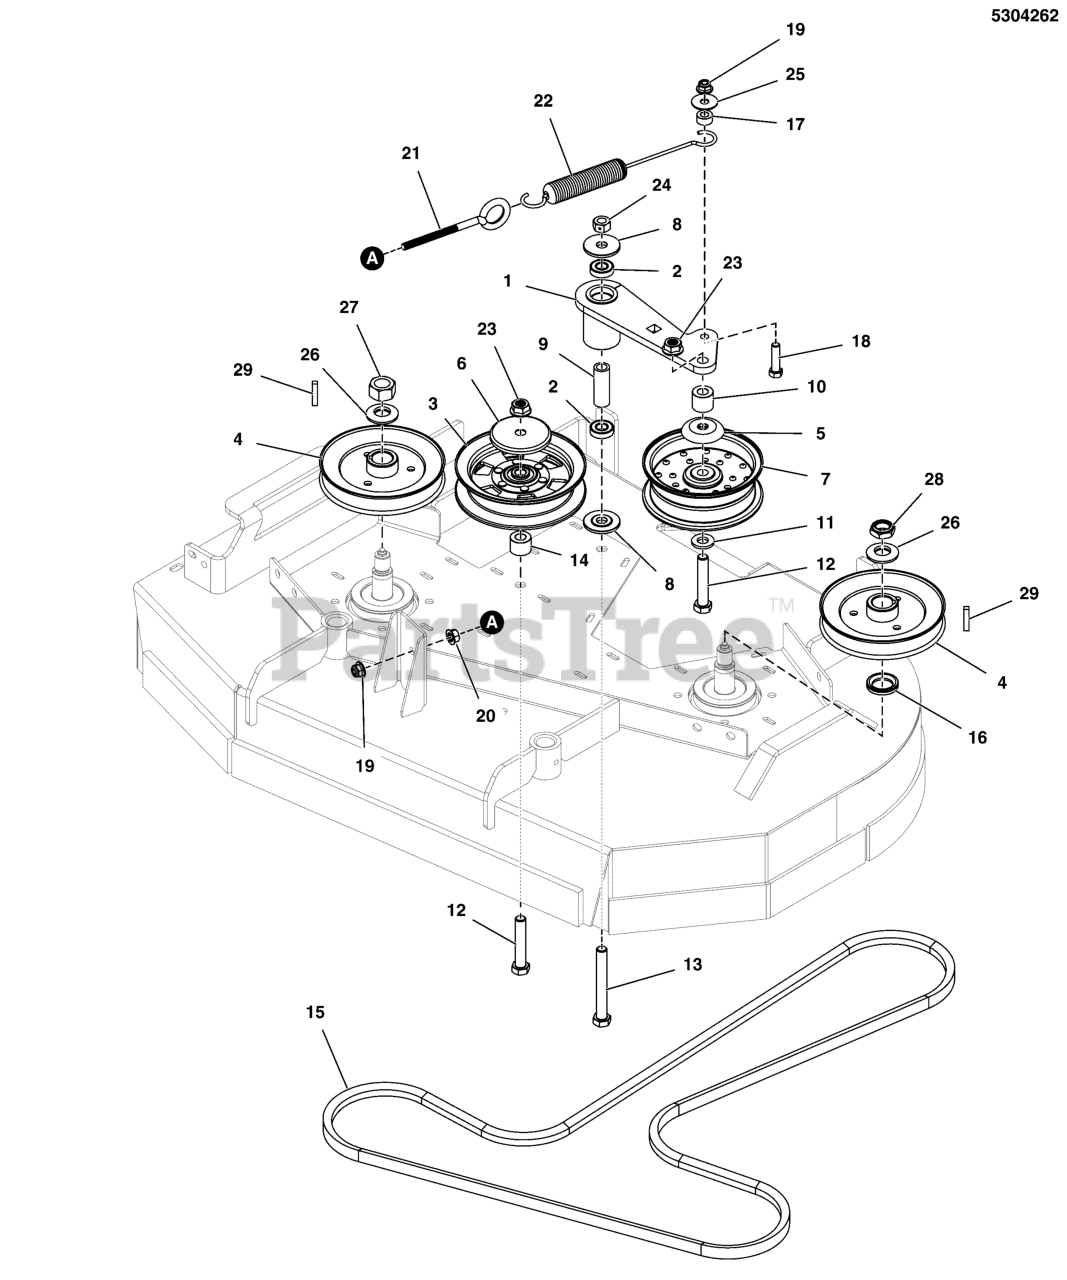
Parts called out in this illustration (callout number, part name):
1	WELD, IDLER ARM, DECK DRIVE, W25 36 -BLK
2	BEARING, BALL, AXLE
3	PULLEY,IDLER,BACKSIDE,NOSEAM 6.25ODX.5ID
4	PULLEY, 5.926OB X .985ID, SINGLE B-SEC
5	SHIELD, PULLEY BEARING, CZ
6	SHIELD, BEARING, 1/2 ID X 2-7/8 OD, CZ
7	PULLEY, IDLER, 5.00 WIDE W/ .51 BORE
8	SPACER, IDLER ARM, 1/2, PM
9	SPACER, .505 X .75 X 2.085, CZ
10	SPACER, .52 X 1.00 X .88, PM, CZ
11	WASHER, 1/2 GD9 CZ
12	BOLT, 1/2-13 X 2-3/4 GD5 CZ
13	BOLT, 1/2-13 X 4" GD5 CZ
14	SPACER, .52 X 1.00 X .75, CZ
15	BELT, B-SEC, 97.6"EL, ARAMID, WRAPPED
16	SPACER, 1.00 X 1.50 X .25, CZ
17	SPACER, .39 X .75 X .38, PM, CZ
18	BOLT, 3/8-16 X 1-1/2" GD5 CZ
19	NUT, 3/8-16 HEX NYLOCK FLANGE
20	NUT, 3/8-16 HEX SERRATED FLANGE
21	EYE BOLT, 3/8-16 X 6, 3THRD, 1EYE, CZ
22	SPRING-EXT, 1.04 ODX10.535LGX.148WR, BLK
23	NUT, Hex Flange, Nylock, 1/2-13
24	NUT, 1/2-13 HEX SIDE LOCK
25	WASHER-3/8 FENDER
26	WASHER, 3/4 BELLEVILLE CL/ZC
27	NUT, 3/4-16 HEX
28	NUT, 3/4-16, HEX JAM NYLON LOCK
29	KEY, 1/4 SQ X 1-1/4
